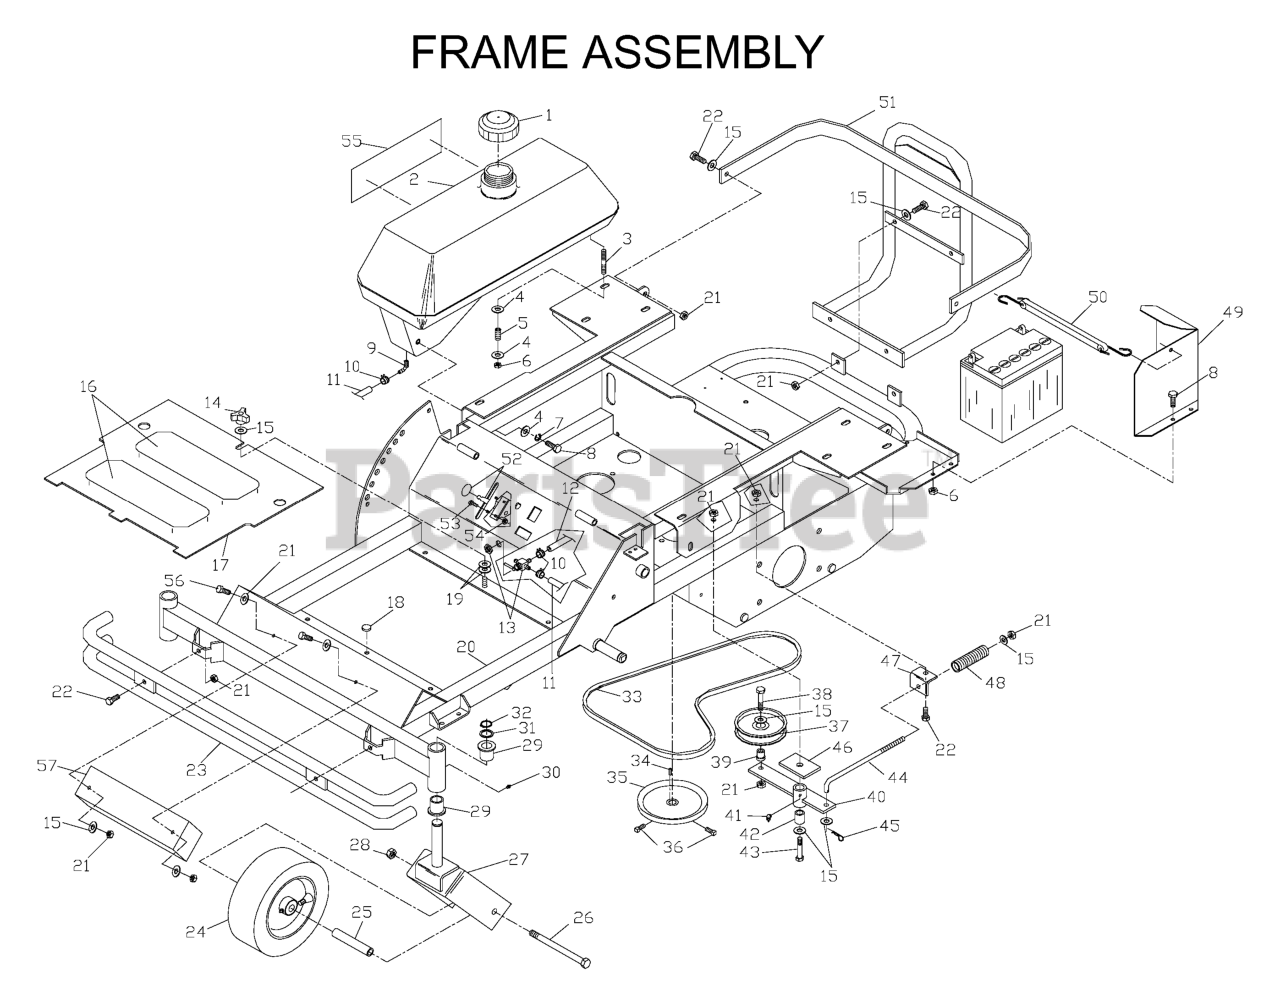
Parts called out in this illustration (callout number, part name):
3	STUD, 5/16C
4	WASHER 5/16 FLAT
6	NUT 5/16C CENTERLOCK
7	WASHER.LOCK.HVY.HLCL.SPR.5/16
8	HCS 5/16C X 3/4
9	HOSE BARB 90 DEGREE
10	HOSE CLAMP
11	FUEL LINE 21.5" TANK
12	FUEL LINE, ENGINE
13	FUEL VALVE
14	KNOB, THREE PRONG
15	WASHER 3/8 FLAT
16	ANTI-SKID PAD
17	FOOTPLATE
18	GROMMET, BUMPER
19	WASHER, 3/8 DISC SPRING SPEC
20	FRAME W/DECALS
21	NUT 3/8C CENTERBLOCK
22	HCS 3/8-16X1.GRD.5.ZD
23	BUMPER, FRONT
24	TIRE, CASTER (COMPLETE)
26	HCS 1/2C X 5 1/2
27	YOKE WELDMENT ORANGE
28	NUT 1/2-13 HEX NYLOC ZD
29	BUSHING, FLANGED
31	BSHG .875 X 1.375 X .074 ZD
32	RETAINING RING, 7/8"
34	KEY 5 MM SQ X 25 MM
36	SCREW 5/16C X 5/8 SQ HEAD
37	IDLER PULLEY
38	HCS 3/8-16 X 1 3/4 GR5
39	BUSHING, IDLER FLANGE
40	IDLER ARM WELDMENT
41	ZERK
42	PIVOT BUSHING
43	HCS 3/8C X 3
44	TENSION ROD
45	HAIRPIN #2
46	SUPPORT PLATE
47	TENSION BRACKET
48	COMPRESSION SPRING
49	BATTERY GUARD W/DECALS
50	BATTERY STRAP
51	ENGINE GUARD W/DECALS
52	THROTTLE CABLE
53	HCS #10-24 X 1/2
54	NUT 10-24 NYLOC
56	HCS 3/8C X 2 1/4
57	WEIGHT BLOCK
539102484	BEARING RETAINER
539103300	ZERK
539103495	TIRE.11X4.00-5NHS.4PR.SMOOTH
539103496	ROLLER BEARING 2 1/4"
539917785	ROLLER BEARING 1"
